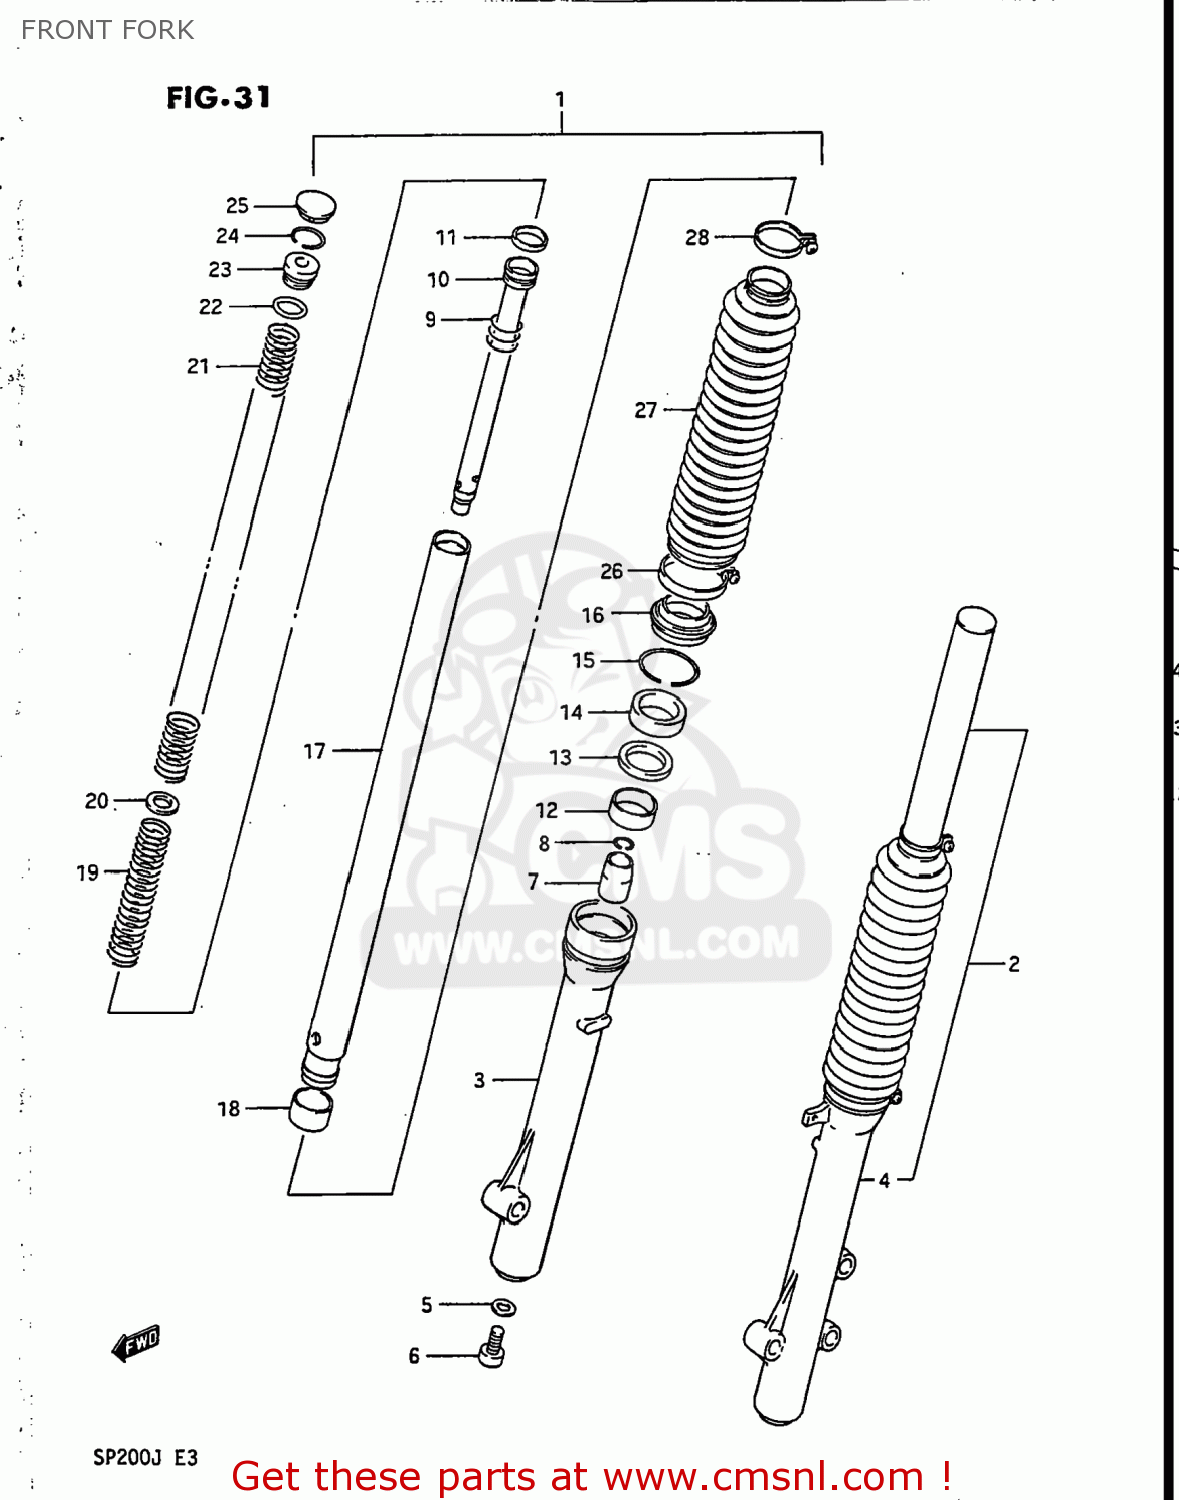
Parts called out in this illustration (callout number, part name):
1	DAMPER ASSEMBLY,FRONT FORK,RIGHT
2	DAMPER ASSEMBLY,FRONT FORK,LEFT
3	TUBE,OUTER,R
4	TUBE,OUTER,L
5	GASKET (NAS)
6	BOLT(8X27)
7	PIECE,OIL LOCK
8	RING,STOPPER
9	SPRING,REBOUND
10	CYLINDER
11	RING,PISTON
12	BUSH,GUIDE
13	SPACER,SEAL
14	OIL SEAL,FRONT FORK
15	CIRCLIP,FORK OIL SEAL
16	SEAL,DUST
17	TUBE,INNER
18	PISTON
19	SPRING,LWR
20	SPRING,JOINT
21	SPRING,UPR
22	O RING
23	SPRING SEAT B
24	RING,STOPPER
25	CAP
26	BAND
27	BOOT
28	BAND
